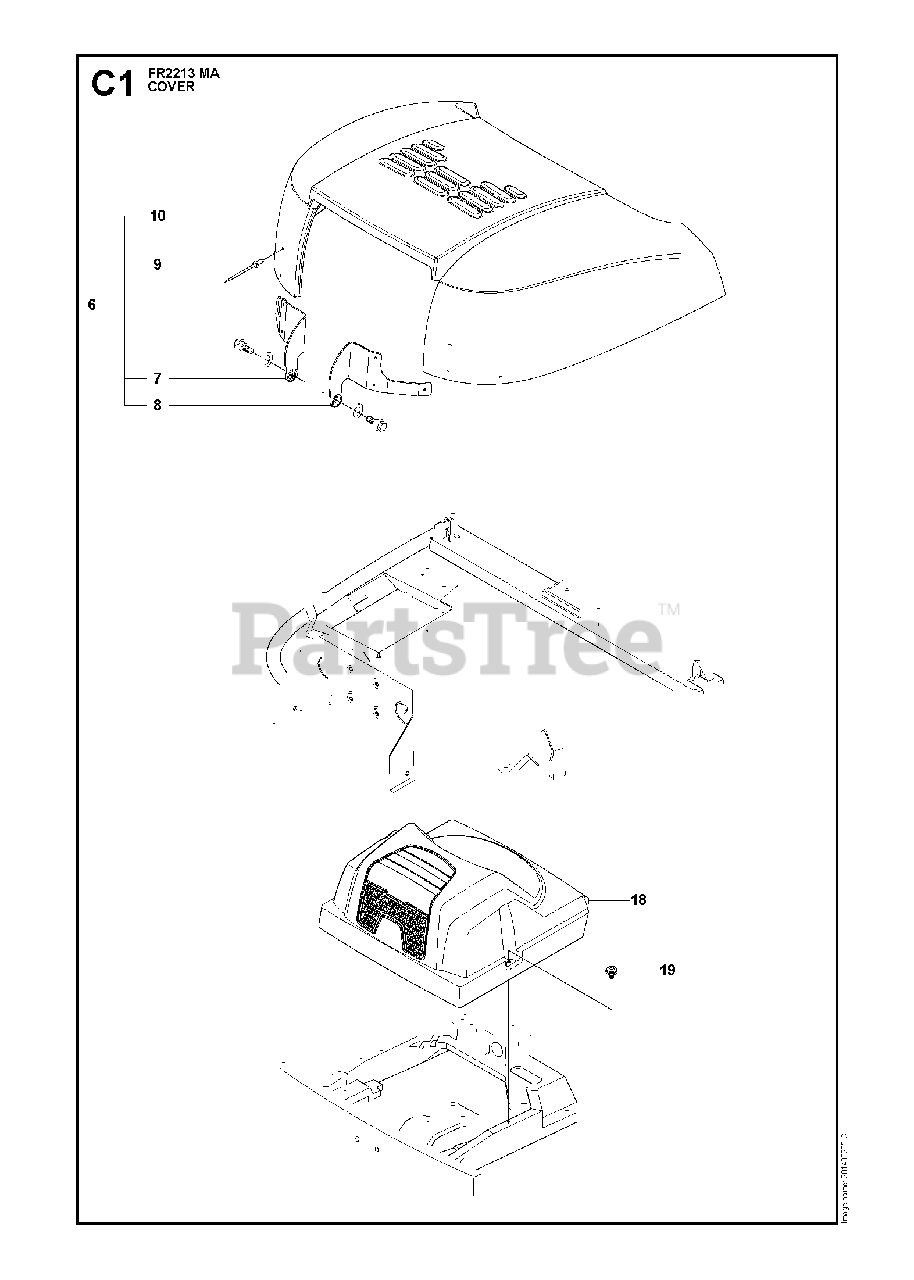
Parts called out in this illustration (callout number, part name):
5	SCREW
9	RIVET
11	BUTTON
12	SUPPORT STRAP
16	NUT
17	SCREW
19	SCREW
21	MAT
22	SCREW
24	SCREW
27	BOLT
28	WASHER
